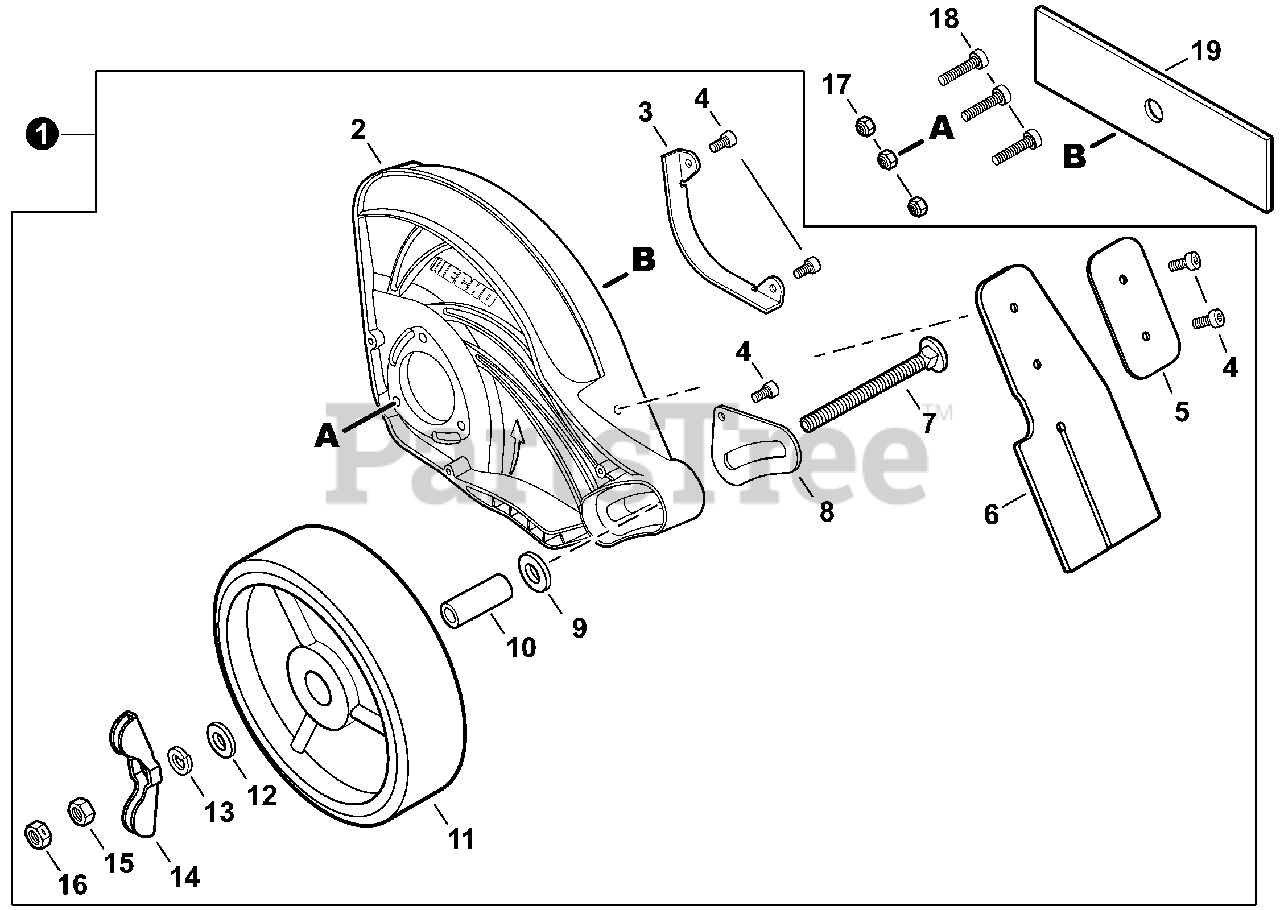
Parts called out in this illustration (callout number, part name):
1	SHIELD KIT, EDGER - PLASTIC
2	SHIELD, BLADE
3	GUARD, SHIELD
4	BOLT, TORX 4×12
5	PLATE, FLAP
6	FLAP, DEBRIS
7	BOLT M8-1.25×80MM
8	BRACKET, WHEEL
9	WASHER 10
10	COLLAR 12
11	WHEEL
12	WASHER 8
13	WASHER, SPRING 8
14	KNOB, FASTENER
16	NUT, LOCK M8
17	NUT, LOCK M5
18	BOLT, TORX 5×25
19	BLADE - 2 PK
